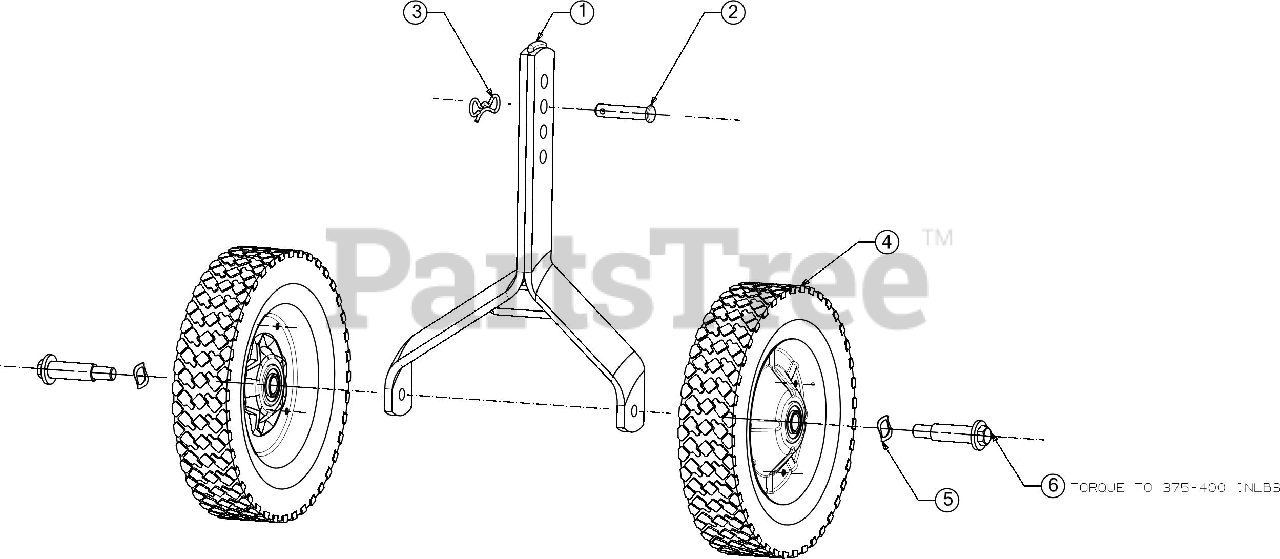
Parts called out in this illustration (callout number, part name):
1	WHEEL BRACKET ASSEMBLY
2	CLEVIS PIN .375 X .1.75
3	PIN:COTTER
4	COMPLETE WHEEL 8X1.75 STORM GRAY
4	BALL BEARING
5	WAVE WASHER
6	SHOULDER SCREW .496X1.44 3/8-16
